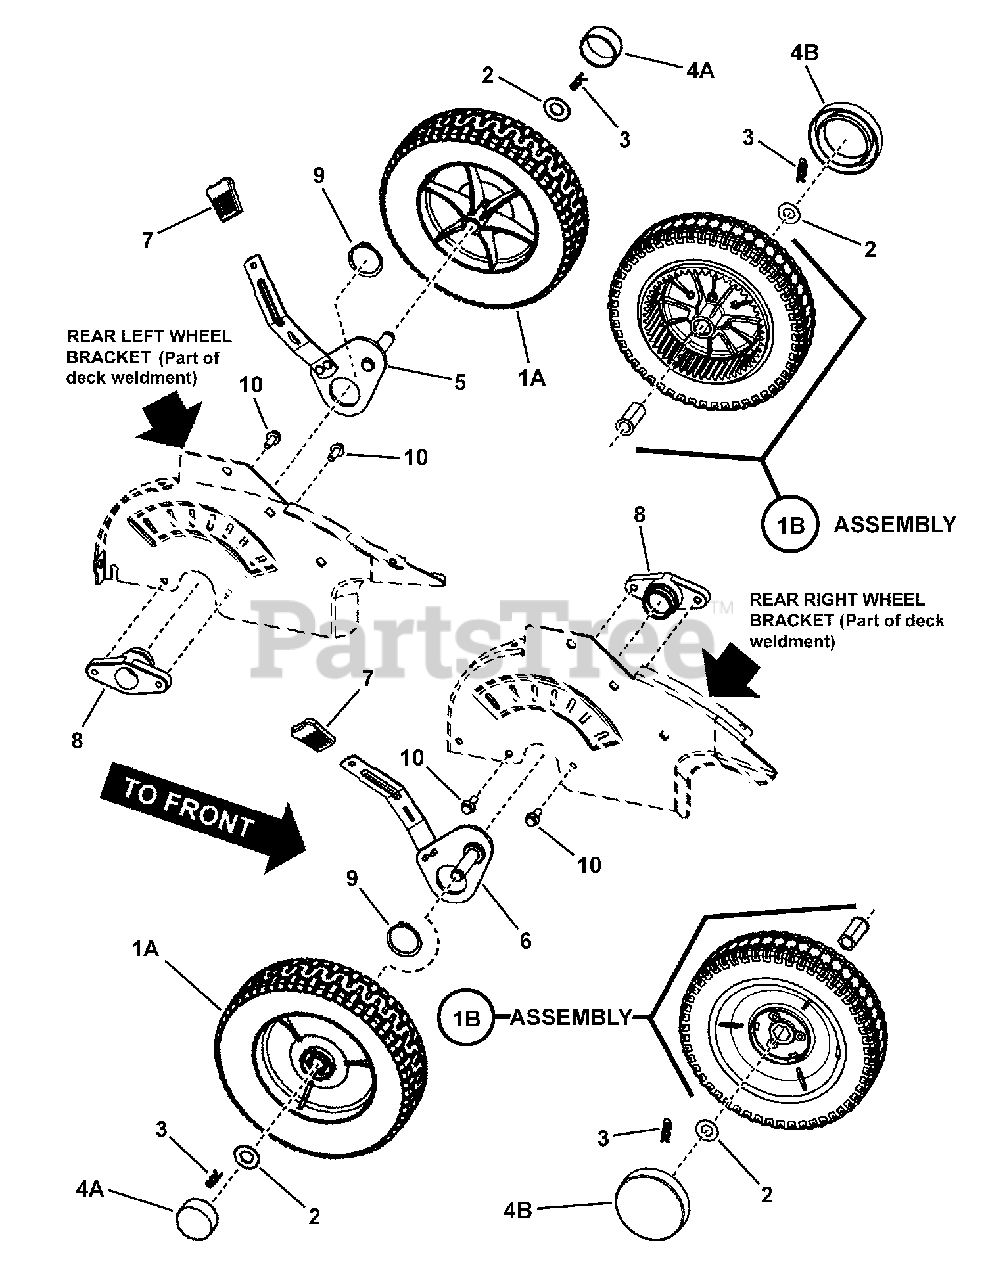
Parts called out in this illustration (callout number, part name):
1A	WHEEL, 9" x 2", LS Tread, w/1-5/8" Hub, Gray
1B	ASSY., 9" x 2" Gear Wheel, Double Bar II Tread & Nylon Bushing
2	WASHER, 1/2" Flat
3	COTTER, Hairpin
4A	HUB CAP, 1-3/8" Diameter (black)
4B	HUB CAP, 3-1/4" Diameter (black)
5	ASSEMBLY, Axle Arm, Left Rear
6	ASSEMBLY, Axle Arm, Right Rear
7	GRIP, Height Latch
8	HOUSING, Axle Bearing
9	SNAP RING, 1-3/8"
10	BOLT, 1/4-20 x 3/4" Hex Flange Lock
